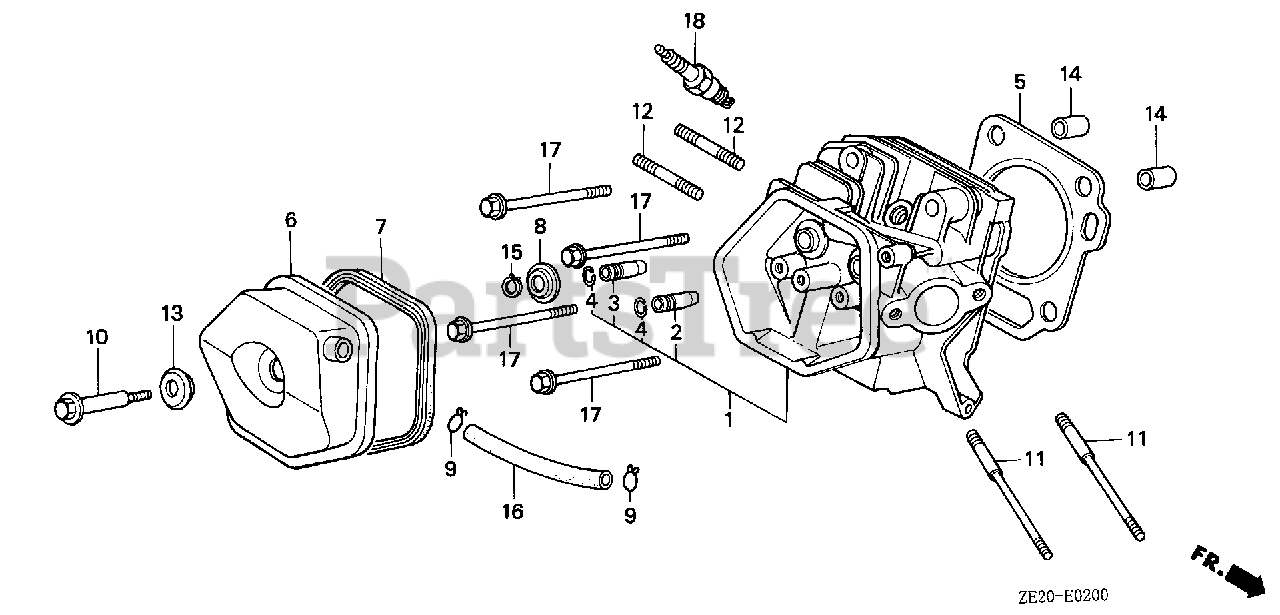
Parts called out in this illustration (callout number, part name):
1	CYLINDER HEAD
1	CYLINDER HEAD (NOT AVAILABLE)
2	GUIDE, VALVE (OVER SIZE)
3	GUIDE, EX. VALVE (OVER SIZE)
4	CLIP, VALVE GUIDE
5	GASKET, CYLINDER HEAD
6	COVER KIT, HEAD
6	COVER, HEAD (NOT AVAILABLE)
7	GASKET, HEAD COVER
8	SEAT, VALVE SPRING
10	BOLT, HEAD COVER
11	BOLT, STUD (8X123)
12	BOLT, STUD (8X47)
13	WASHER, HEAD COVER
14	PIN, DOWEL (12X20)
15	CIRCLIP (OUTER) (11MM)
16	BULK HOSE, VACUUM (11X1000) (11X105)
16	BULK HOSE, VACUUM (8X1000) (8X100)
17	BOLT, FLANGE (10X80)
18	SPARK PLUG (W16EPR-U) (DENSO)
18	SPARK PLUG (BPR6ES) (NGK)
18	SPARK PLUG (W20EPR-U) (DENSO)
